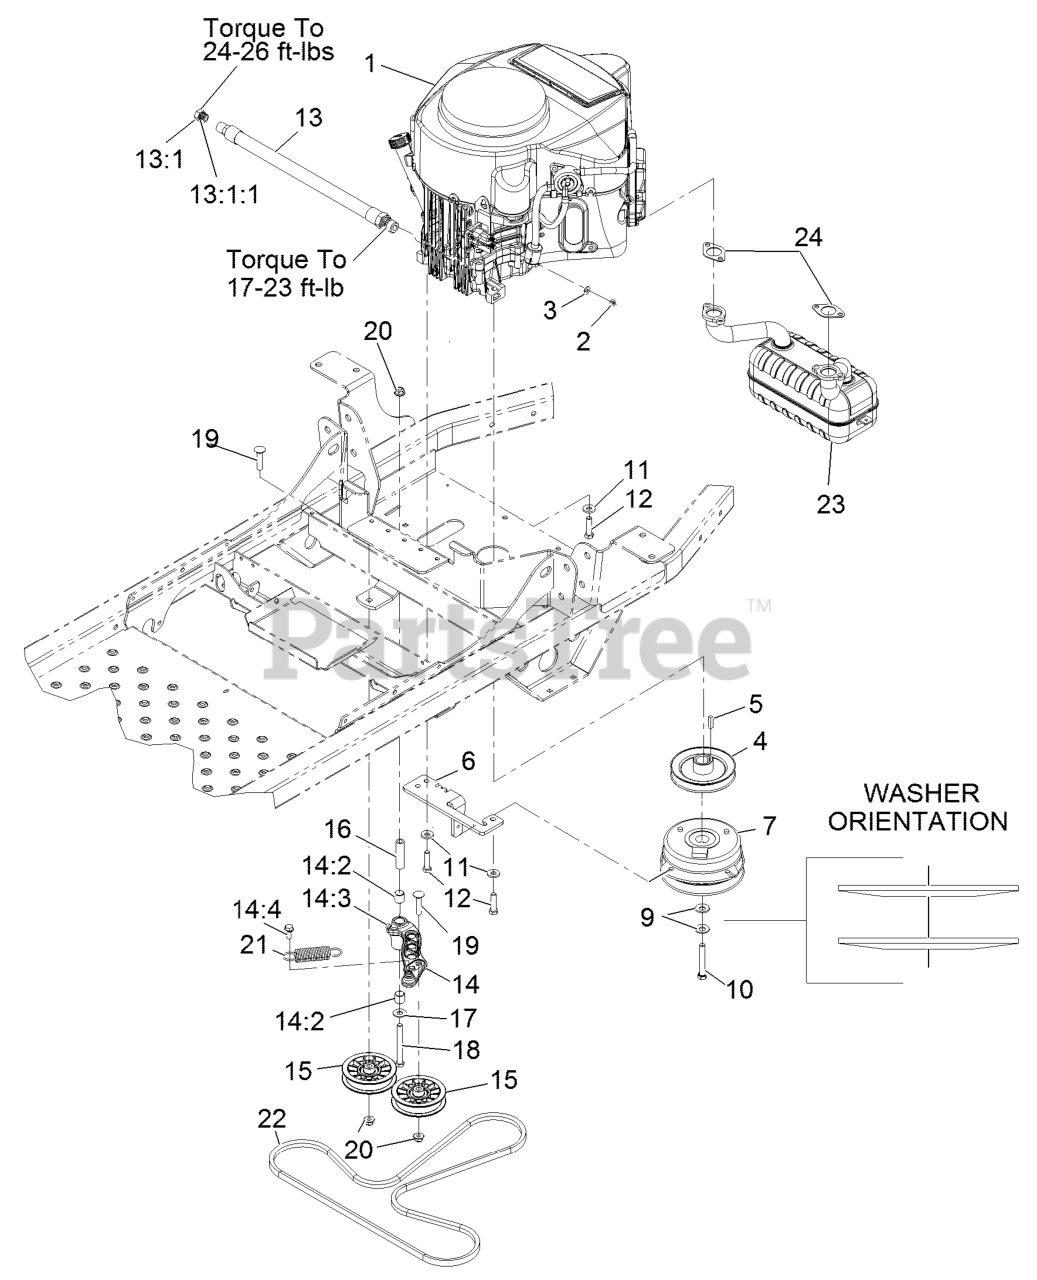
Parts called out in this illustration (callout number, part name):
1	Engine-Kawasaki
2	NUT-HEX
3	WASHER-FLAT
4	SHEAVE-SPLIT STEEL
6	ANCHOR-CLUTCH
7	CLUTCH,125FTLB 1.0 B
9	WASHER-SPRING
10	SCREW-HH W/LOCTITE
11	WASHER-BELLEVILLE
12	SCREW-HH
13	ENGINE OIL DRAIN HOSE ASM
13:1	PLUG-HH
13:1:1	O-RING
14	IDLER ARM ASM
14:2	SLEEVE-BEARING
14:3	FITTING-GREASE, 90 DEG
14:4	SCREW-THD ROLL, HWH
15	PULLEY-FLAT IDLER
16	BUSHING-PIVOT, IDLER
17	WASHER-FLAT
18	SCREW-CARR
19	SCREW-CARR
20	NUT-HF, NI
21	SPRING-EXTENSION
22	V-BELT
23	MUFFLER-KAWASAKI
24	GASKET-EXHAUST
